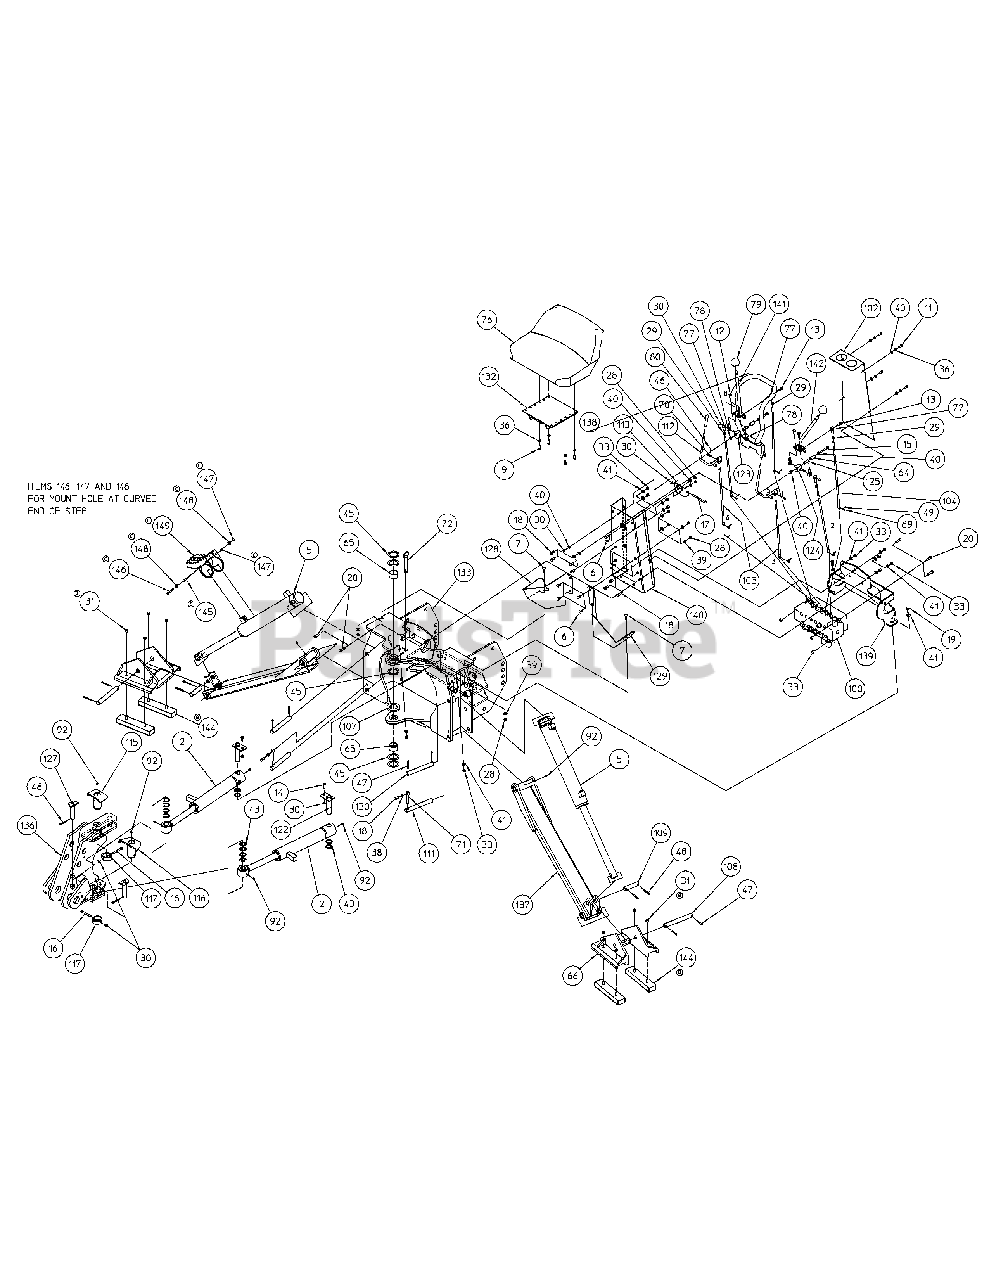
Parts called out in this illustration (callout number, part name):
1	Hydraulic Cylinder - Bucket
2	Hydraulic Cylinder - Swing
3	Hydraulic Cylinder - Boom
4	Hydraulic Cylinder - Dipper
5	Hydraulic Cylinder - Stabilizer
6	Bolt, Carriage 5/16 NC x 3/4"
7	Bolt, Carriage 5/16 NC x 1-1/4"
8	Bolt, 1/4 NC x 3/4"
9	Bolt, 5/16 NC x 3/4"
10	Bolt, 5/16 NC x 3/4" Thread Forming
11	Bolt, 5/16 NF x 3/4"
12	Bolt, 5/16 NF x 7/8"
13	Bolt, 5/16 NF x 1" Gr. 5
14	Bolt, 5/16 NF x 1.125" Gr. 5
15	Bolt, 5/16 NF x 2-1/4" Gr. 5
16	Bolt, 5/16 NF x 2.75" Gr. 8 SAE
17	Bolt, 5/16 NF x 4" Gr. 8
18	Bolt, 3/8 NF x 3/4"
19	Bolt, 3/8 NF x 1"
20	Bolt, 3/8 NF x 1-1/4"
21	Bolt, 3/8 NF x 2.5"
22	Bolt, 3/8 NF x 2-3/4"
23	Bolt, 3/8 NC x 5-1/2" Long Gr. 5
24	Bolt, 1/2 NF x 1"
25	Bolt, 1/2 NF x 3.25"
26	Nut, 1/4 NC
27	Nut, 5/16 NC
28	Locknut, 5/16 NC
29	Nut, 5/16 NF
30	Locknut, 5/16 NF
31	Locknut, 3/8 NC
32	Nut, 3/8 NF
33	Locknut, 3/8 NF
34	Locknut, 1/2 NF
35	Lockwasher, 1/4
36	Lockwasher, 5/16
37	Lockwasher, 3/8
38	Lockwasher, 3/8
39	Flat Washer, 5/16 STD
40	Washer, 5/16 SAE
41	Flat Washer, 3/8 SAE
42	Flat Washer, 1/2" Hardened
43	Machine Bushing, 1-1/2" OD x 1" ID x 18Ga.
44	Machine Bushing, 1-7/8" OD x 1-1/4" ID x 18Ga.
45	Machine Bushing, 2-1/2" OD x 1-3/4" ID x 18 Ga.
46	Cotter Pin, 3/32" Dia x 3/4"
47	Cotter Pin, 3/16" Dia x 1-1/2"
48	Cotter Pin, 1/4" Dia x 1-1/2"
49	Hair Pin Cotter, 3/64" Dia x 11/16"
51	Adapter Union, 9/16-18M x 3/8NPTF
52	Adapter Union, 9/16-18M x 3/8NPSM
53	Adapter Union, 3/4-16M x 3/8NPTF x Straight
54	Adapter Union, 3/8NPTM x 3/8NPTF x 90 degree
55	Adapter Union, 9/16-18M x 3/8NPTF x 90 degree
56	Adapter Union, 7/8-14M x 1/2NPSM x 90 degree
57	Adapter Union, 3/4-16M x 3/8NPTF x 90 degree
58	Adapter Pipe, 3/4-16NFM x 1/2NPTF
60	Coupler Nose, 3/4-16F Thread
62	Coupler Body
63	Garlock Bearing
64	Bronze Bearing
65	Garlock Bearing, 028DxR016
66	Stabilizer Pad
67	Cast Guide Link
68	Bucket Link
69	Clevis Pin, 3/16" Dia x 5/8"
70	Clevis Pin, 1/4" Dia x 7/8"
71	Pin Retainer
72	Swing Lock Pin
74	SMV Socket
75	SMV Bracket
77	Ball Joint - Shouldered
78	Ball Joint
79	Control Knob
80	Rubber Cap
81	Plastic Tie T150L
82	Plastic Tie T120L
83	Plastic Tie T50L
85	Hose Sleeve FC45-16 x 30" Long
86	Hose Sleeve FC425-16 x 19" Long
87	Hose Sleeve FC425-16 x 48" Long
88	Hose Sleeve FC425-16 x 63" Long
89	Hose Sleeve FC425-16 x 79" Long
90	Hydraulic Fluid
91	Grease Fitting
92	Grease Fitting (Two are part of #000187 Cyl.)
93	Hydraulic Hose, 3/8NPTM x 3/8NPTM x 20" long
94	Hydraulic Hose, 3/8NPTM x 3/8NPTM x 36" long
95	Hydraulic Hose, 3/8NPTM x 3/8NPTM x 80" long
96	Hydraulic Hose, 3/8NPTM x 3/8NPTM x 60" long
97	Hydraulic Hose, 3/8NPTM x 3/8NPTM x 105" long
98	Hydraulic Hose, 3/8NPTM x 3/8NPTM x 125" long
99	Hydraulic Hose, 1/2NPTM x 1/2NPTM x 54" long
100	Control Valve
101	Adapter Union, 7/16-20M x 3/8NPTF
102	Rear Shroud
103	Stabilizer Lever Control Rods
104	Control Rod
105	Buck Link Pin
106	Pivot Pin, Boom Cyl. Rod 1-1/4" Dia. x 6" Long
107	Thrust Washer
108	Stab Pivot Shaft
109	Stabilizer Cylinder Pin
110	SMV Socket Mount
111	Stabilizer Pivot Pin
112	Stabilizer Control Lever
113	Lever Bracket
114	Hose Clamp - Short
115	Upper Pivot Pin Weldment
116	Lower Pivot Pin Weldment
117	Retaning Collar
122	Swing Cylinder Pin Weldment
123	RH Pivot Weldment
124	LH Pivot Weldment
126	Pivot Pin Weldment, Boom 1-3/4" Dia. x 2-3/4" Lg
127	Swing Cylinder Pin Weldment
128	RH Toe Shield
129	LH Toe Shield
130	Cylinder Base Pin
131	Hose Clamp - Long
132	Seat Plate Weldment
133	Mainframe Weldment
134	Dipper Weldment
135	Boom Weldment
136	Swing Frame Weldment
137	Stabilizer Weldment
138	Grab Bar Weldment
139	Valve Mount Weldment
140	Front Shroud Weldment with Decals
141	RH Joystick Weldment
142	LH Joystick Weldment
144	Rubber Street Pad
145	Bolt, Hex 1/4-20 x 1.750 Gr 5
146	Bolt, Hex 1/4-20 x 2.0
147	Nut, hex 1/4-20 Gr 5 Lock
148	Flat Washer, 1/4 Hardened
149	Step Weldment
150	Adapter Union, 45 degree
